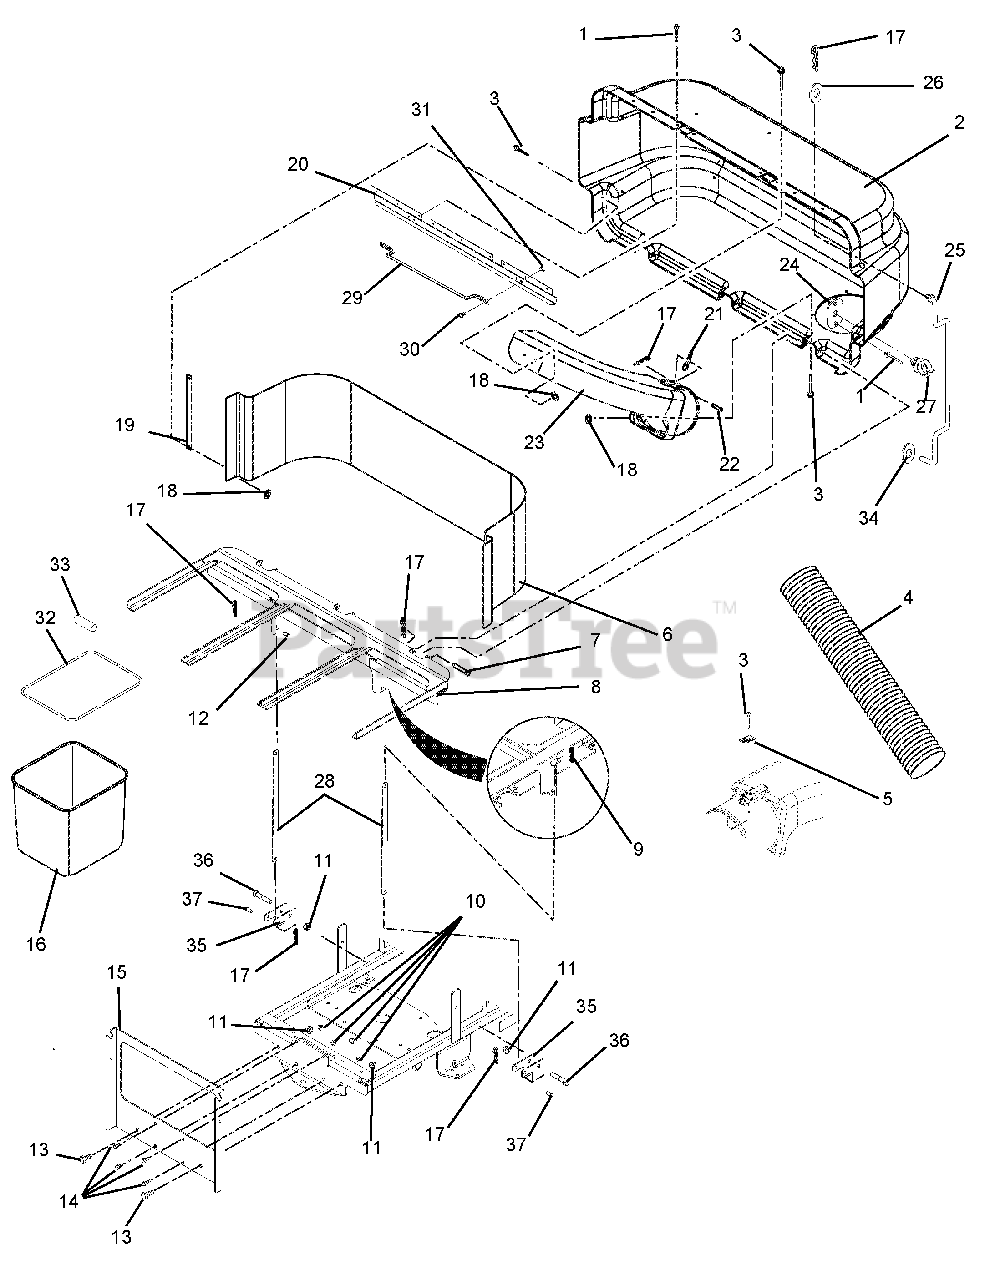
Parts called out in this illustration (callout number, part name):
1	RVT-POP .187X.402 DOME ST
2	BAGGER COVER W/DECAL
3	RVT-POP .187X.375
4	HOSE,7X38 KANAFLEX 165CL
5	THUMB LATCH
6	SCREEN, BAGGER
7	PIN-CLEV .371X3.25 YWZC
8	WMT, BAGGER FRAME
9	PIN, HAIR, EXT - #16 YWZC
10	@NUT-LK-NYL-FLG .38-16 YWZC
11	@NUT-LK-NYL-FLG .50-13 YWZC
12	PIN-CLEV .38X.75 YWZC
13	@BLT-HEX .50-13X1.00 GR5 YWZC
14	@BLT-HEX .38-16X1.00 GR5 YWZC
15	MNT, REAR BAGGER
16	BAG, ZOOM MESH
17	PIN-HAIR, ENDRIES #25 YWZC
18	@WSHR-FL-STL.219X.50X.049 YWZC
19	STRAP,COVER
20	LATCH, BAGGER (ZOOM)
21	INDICATOR, FLOW
22	PIN-CLEV .309 X 1.625 YWZC
23	BOOT,UPPER
24	PLATE, ROD CLIP
25	PROP-ROD, BAGGER
26	@WSHR-FL-STL.406X.812X.065 YWZ
27	CLIP-.38
28	STRAP, REINF.
29	BAGGER HANDLE
30	@BLT-RDHDSQNK .25-20X.75 G5YZ
31	@NUT-LK-TOP-FLG .25-20 YWZC
32	FRAME, ZOOM BAG
33	HOSE, .38 X.50 X 3.00 VINYL
34	RETAINER, .38 PUSH-ON
35	CLAMP, ZOOM BAGGER MNT
36	@BLT-HEX .50-13X2.75 GR5 YWZC
37	PIN, CLEV .371 X 2.12 YZ
